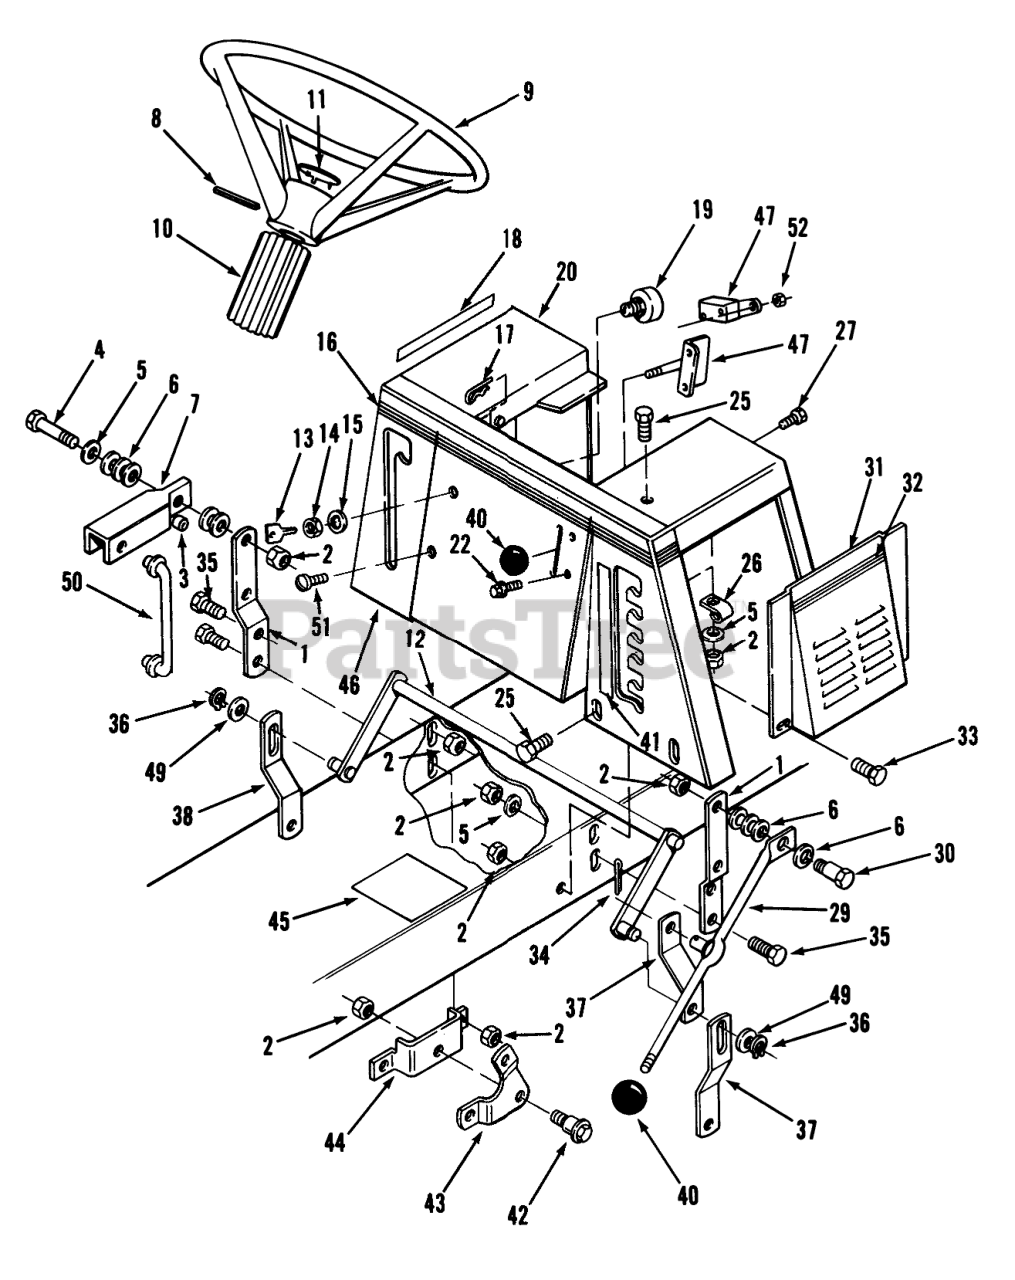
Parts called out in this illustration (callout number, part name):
1	Bracket
2	NUT-LOCK, NI
3	SPACER
4	SCREW-HH
5	WASHER-PLAIN
6	WASHER-BELLEVILLE
7	SHIFT LEVER WA B
8	PIN-ROLL
9	Steering Wheel Assembly (Includes Reference #11)
10	COVER-STEERING SHAFT
11	STEERING WHEEL INSERT
12	Arm
13	KEY-IGNITION
14	NUT-HH
15	WASHER-TOOTH, INTERNAL
16	DECAL-UPPER DECK ENGAGE
17	PIN-COTTER
18	DECAL - SHIFT PATTERN
19	Switch-Ignition (Incl. Ref. #6-8)
20	SEAT BODY WA R
21	DECAL-FRT SEAT CONTROLS
22	SCREW-HWHTF
23	Knob
24	THROTTLE CONTROL
25	SCREW-HH
26	CLAMP
27	SCREW-HH
28	DECAL - UPPER HOC
29	HOC LEVER WA B
30	BOLT-SHOULDER
31	L/H SEAT BASE PANELR
32	DECAL - LH TORO 8-32
33	SCREW-HH
34	PIN-COTTER
35	SCREW-HH
36	RING-RETAINING
37	HOC ENGAGE BRKT R
38	Link-Deck Suspension
39	NUT-LOCK, CONE
40	SCREW-HH
41	DECAL - LOWER HOC
42	SCREW-SHOULDER
43	DECK ENGAGE BELLCRANK
44	BELLCRANK MTG BRKT
45	INSTRUCTION DECAL
46	DECAL - USA
47	SWITCH-MICRO
48	DECAL-LOWER DECK ENGAGE
49	WASHER-FLAT
50	BELLCRANK LINK(PLTD)
51	SCREW-SPH
52	NUT-SPEED
